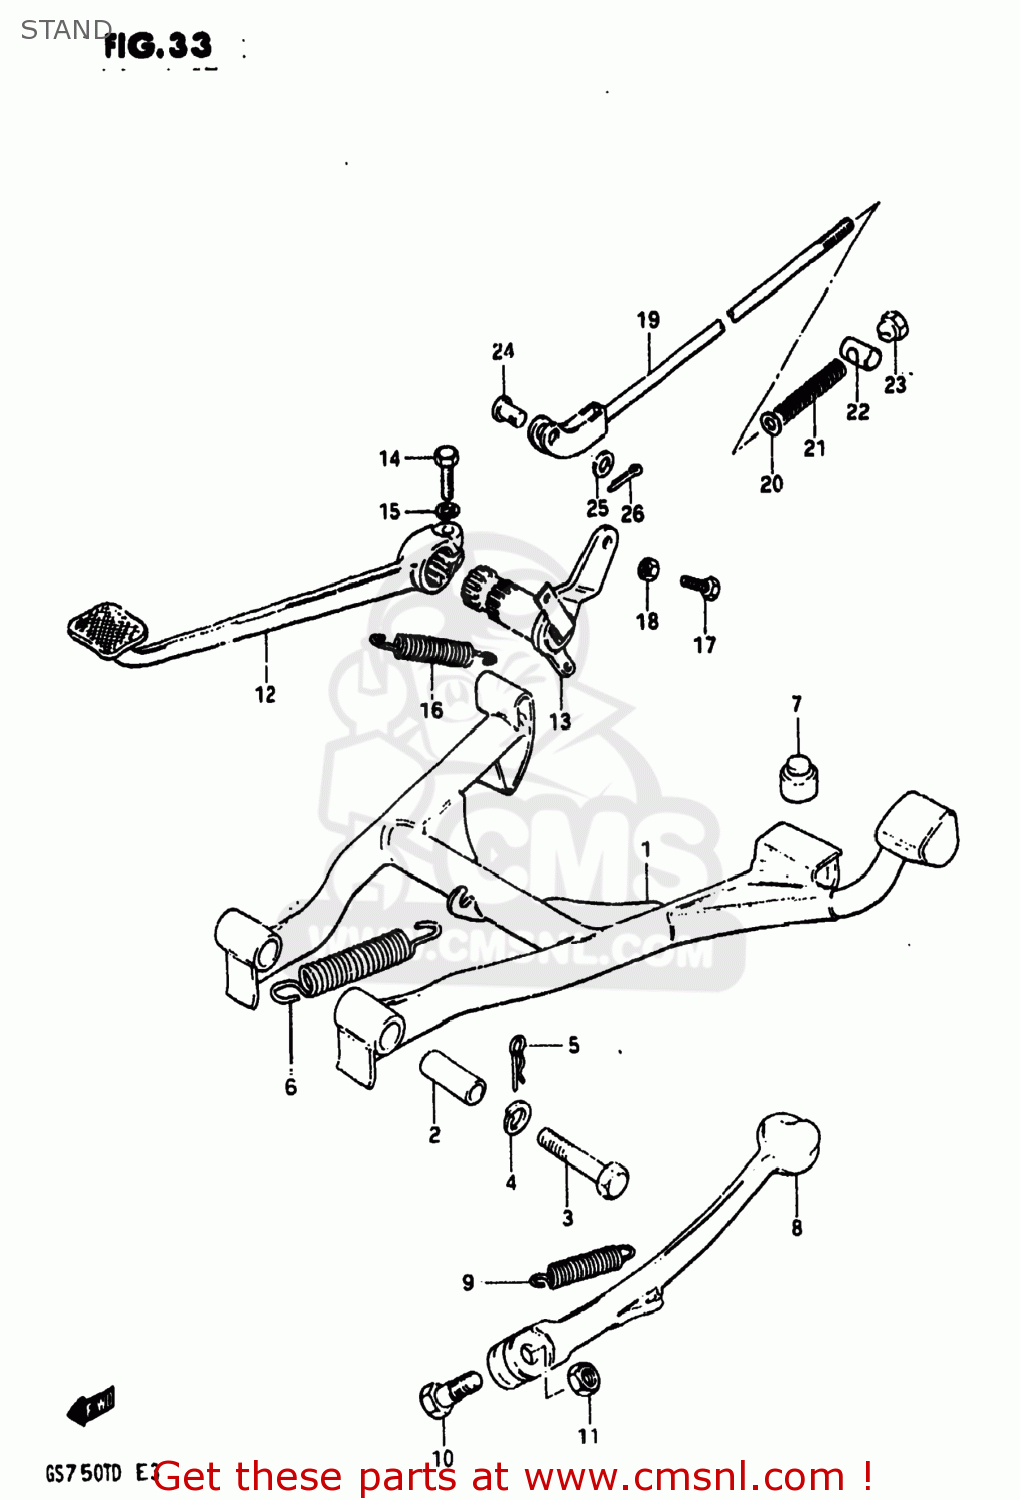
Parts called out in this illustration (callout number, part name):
1	STAND,CENTER
2	SPACER(10X16X38.8)
3	BOLT
4	LOCK WASHER
5	CLIP
6	SPRING
7	CUSHION
8	STAND,SIDE
9	SPRING
10	BOLT(10X30)
11	NUT
12	PEDAL,BRAKE
13	ARM,BRAKE PEDAL
14	BOLT
15	LOCK WASHER
16	SPRING
17	BOLT
18	NUT
19	ROD ASSEMBLY,REAR BRAKE
20	WASHER
21	SPRING
22	PIN
23	NUT
24	PIN(L:13.5)
25	WASHER
26	PIN 20X20
